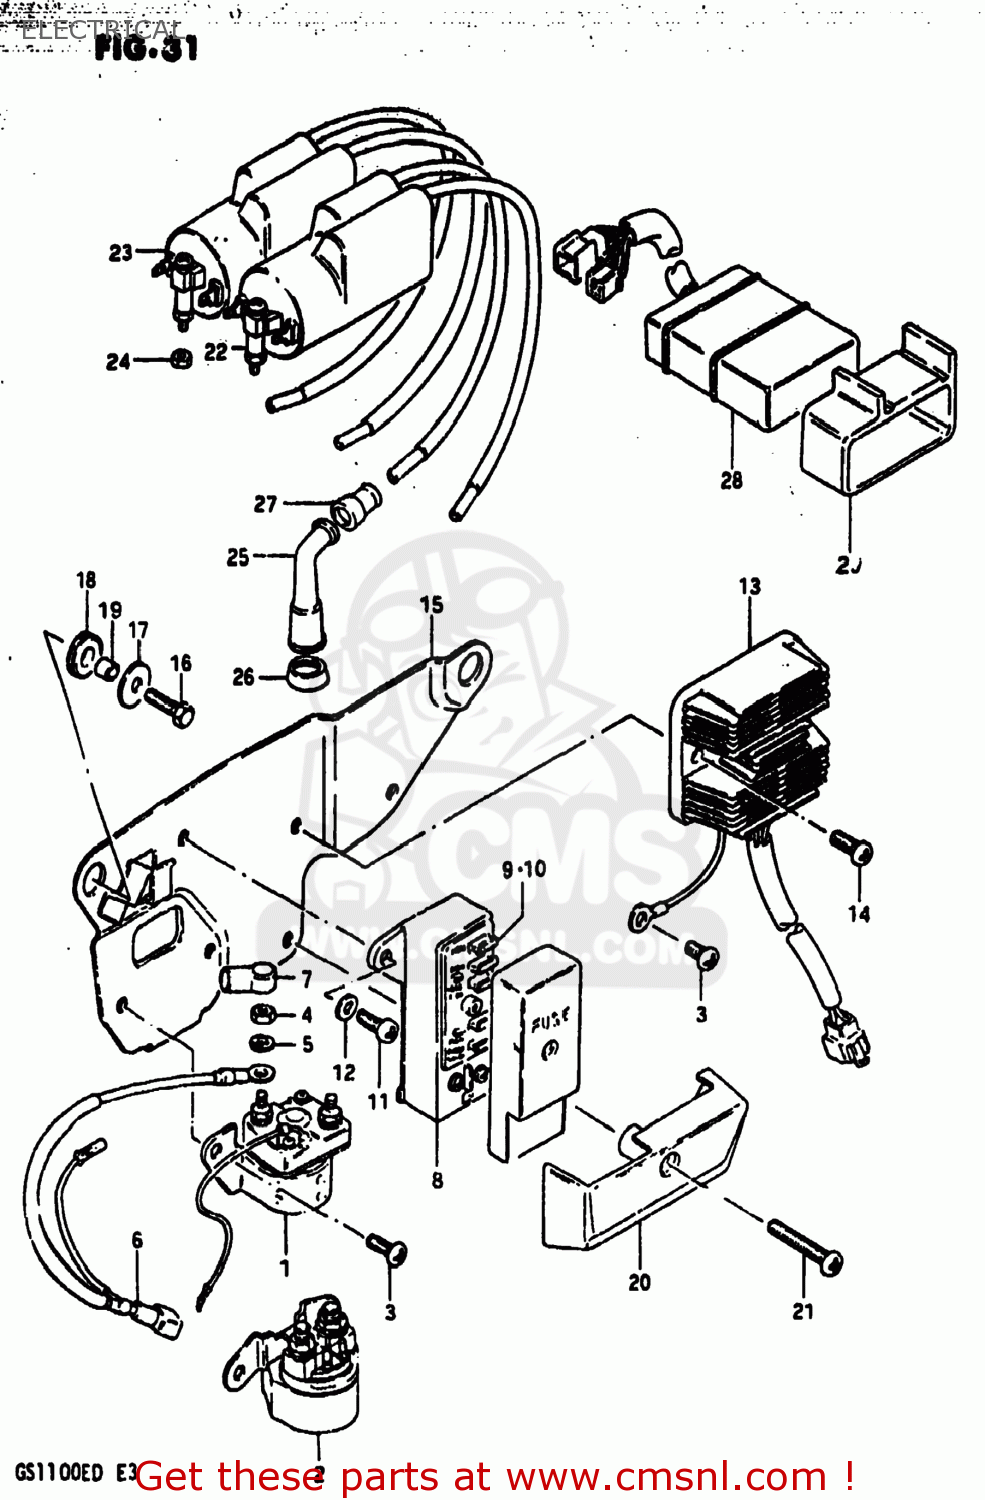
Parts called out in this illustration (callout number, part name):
1	RELAY ASSY,STARTING MOTOR
2	RELAY ASSEMBLY,STARTING MOTOR
3	SCREW
4	NUT 6MM
5	LOCK WASHER
6	CORD,BATTERY MINUS
7	CAP,STARTER RELAY
8	BOX ASSEMBLY,FUSE
9	FUSE(10A)
10	FUSE(15A)
11	SCREW
12	WASHER
13	RECTIFIER ASSEMBLY
14	SCREW 6X12
15	HOLDER COMP,ELECTRONIC PARTS
16	BOLT, UPPER
17	WASHER (6.5X22X1.6)
18	CUSHION
19	SPACER (7X9X7)
20	COVER,ELECTRIC PARTS HOLDER
21	SCREW 6X12
22	COIL ASSEMBLY,IGNITION
23	COIL ASSEMBLY,IGNITION
24	NUT
25	CAP ASSY,SPARK PLUG
26	SEAL,SPARK PLUG
27	SEAL,SPARK PLU
28	RELAY,LAMP OUTAGE WARNING
29	STAY,LAMP OUTAGE INDICATOR
